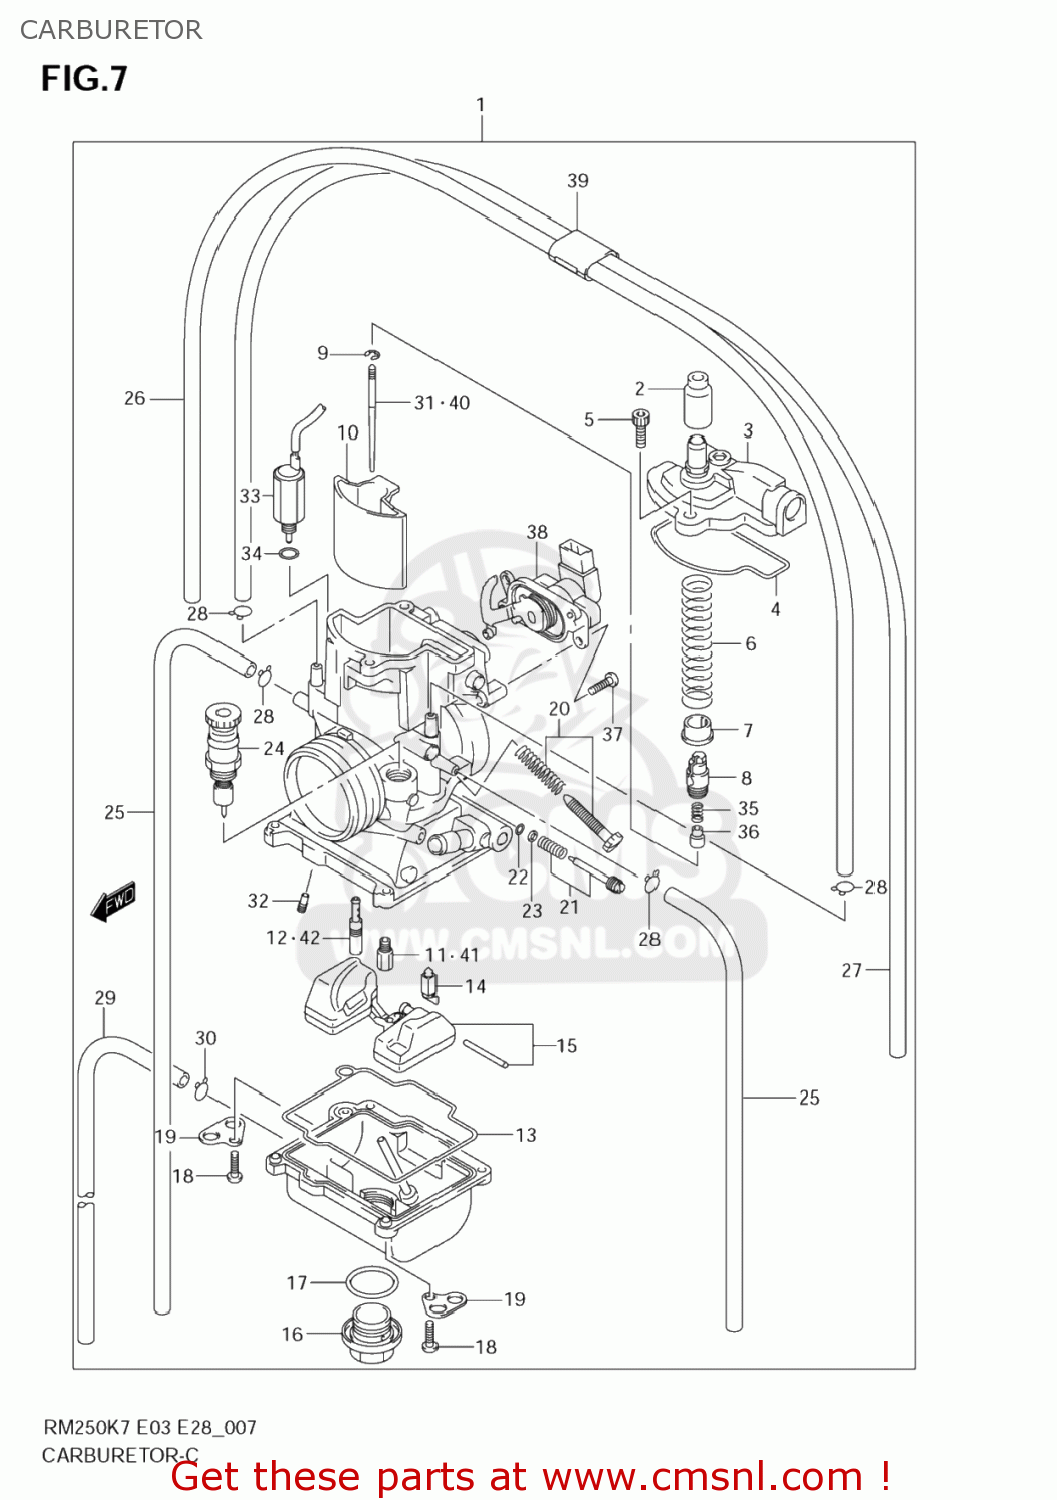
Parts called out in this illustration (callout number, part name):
1	CARBURETOR ASSY
2	CAP,CARBURETOR
3	TOP
4	O RING
5	SCREW
6	SPRING,THROTTLE VALVE
7	COLLAR,THROTTLE VALVE
8	HOLDER,CABLE
9	CLIP,NEEDLE
10	VALVE,PISTON
11	JET,MAIN(168)
12	JET,SLOW(48)
13	GASKET,FLOAT CAHMBER
14	VALVE SET,FLOAT
15	FLOAT SET
16	BOLT,DRAIN
17	O RING
18	SCREW
19	PLATE
20	SCREW SET,STOP
21	SCREW SET,AIR
22	O RING
23	WASHER
24	STARTER VALVE
25	HOSE(4X7X620)
26	HOSE(4X7X620)
27	HOSE(4X7X620)
28	CLIP
29	HOSE(3.5X6.5X600)
30	CLIP
31	NEEDLE,JET(NECJ)
32	JET,POWER(45)
33	SOLENOID ASSY
34	O RING
35	SPRING
36	COLLAR
37	SCREW
38	SENSOR ASSY
39	CLIP
40	NEEDLE,JET(NECF)
41	JET,MAIN(150)
42	JET,SLOW(35)
